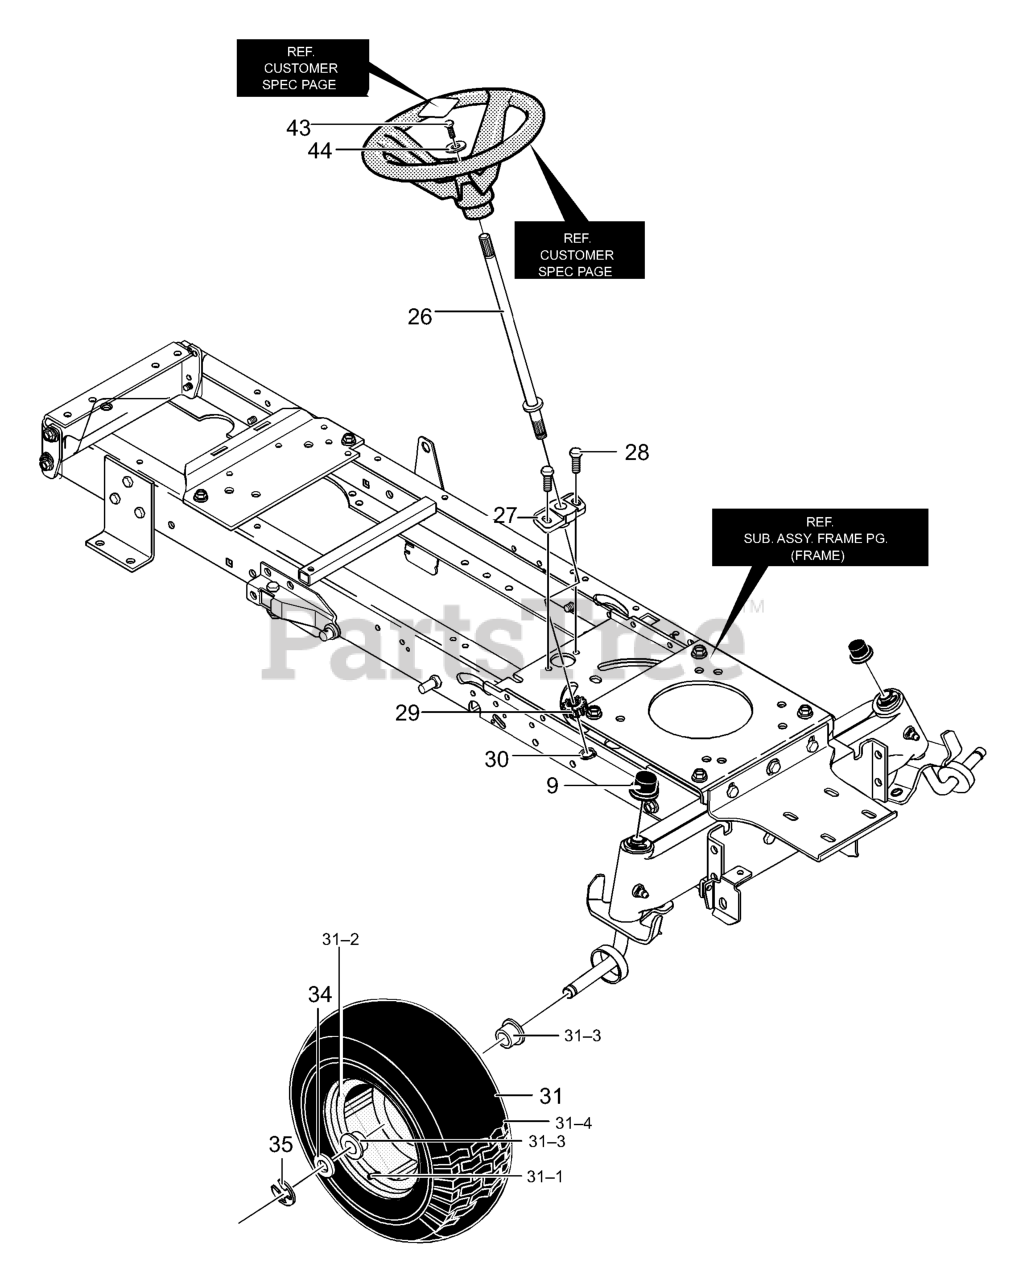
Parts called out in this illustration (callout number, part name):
9	Dust Hub Cap
26	Shaft, Steering
27	Bearing-Lower
28	Screw, 5/16-18 x 0.75
29	Gear, Pinion
30	Retaining Ring
31	Tire & Rim
31-1	Valve Stem
31-3	Bearing
34	Flatwasher
35	E-Ring
43	Screw, 1/4-20x.75
44	Flatwasher
